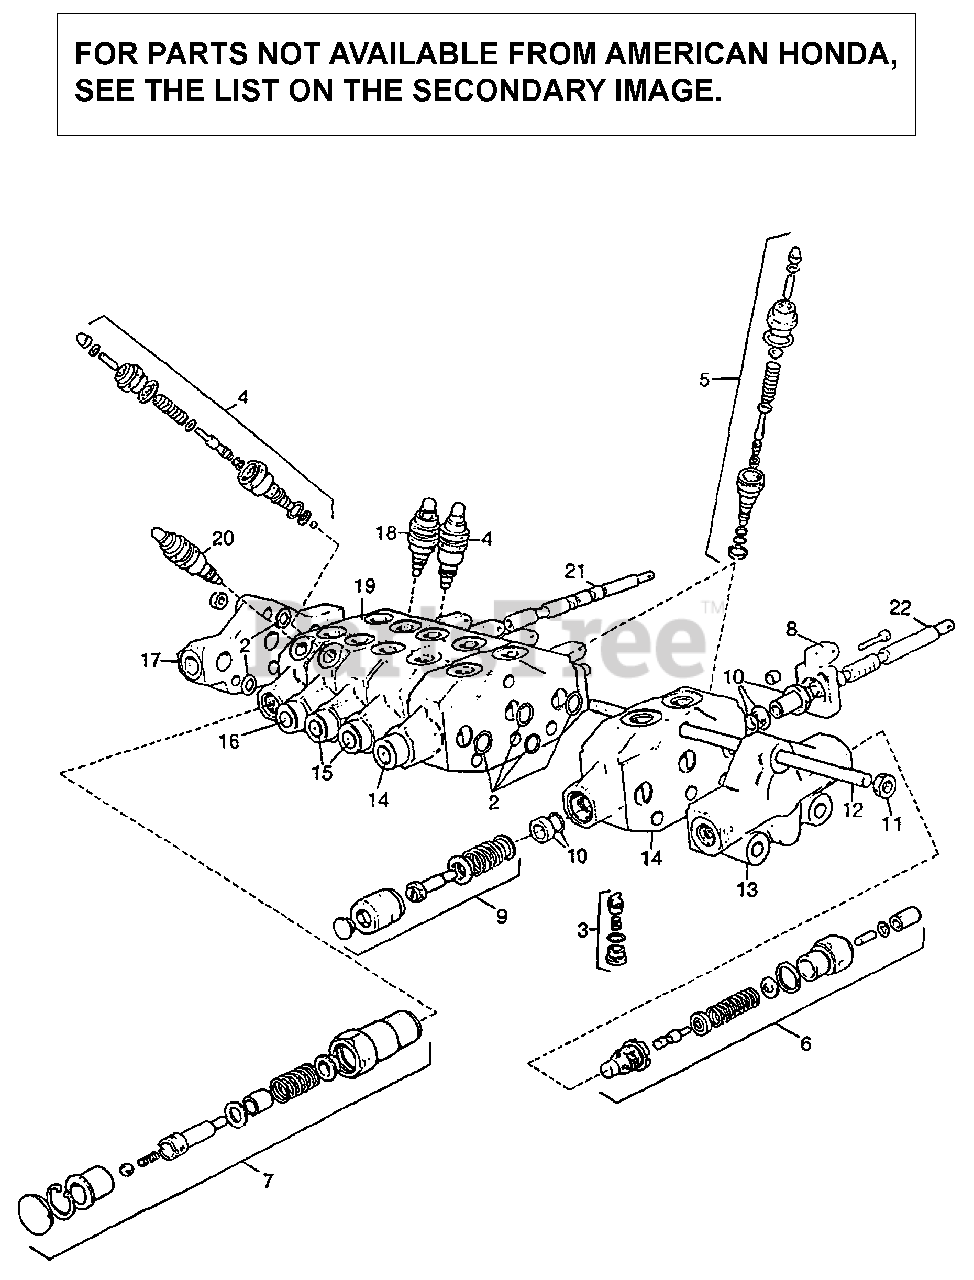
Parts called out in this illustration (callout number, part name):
1	VALVE, CONSOLE
2	REPAIR KIT, SECTION SEAL
3	VALVE ASSY., CHECK
4	VALVE, SHOCK/DAMPENING (2000PSI)
5	VALVE, SHOCK/DAMPENING (2500PSI)
6	VALVE ASSY., RELIEF
7	CONTROL ASSY., SPOOL POSITION
8	CONTROL ASSY., SPOOL POSITION
9	REPAIR KIT, SPOOL
10	TIE ROD (8X276MM)
12	INLET, FR.
13	SEGMENTS, DIPPER STICK AND BUCKET
14	SEGMENT, STABILIZER
15	SEGMENT, SWING
16	EX., STANDARD
17	VALVE, SHOCK/DAMPENING (3500PSI)
18	BRACKET, LEVER
19	SEGMENT, BOOM
20	VALVE, SHOCK/DAMPENING (2500PSI)
